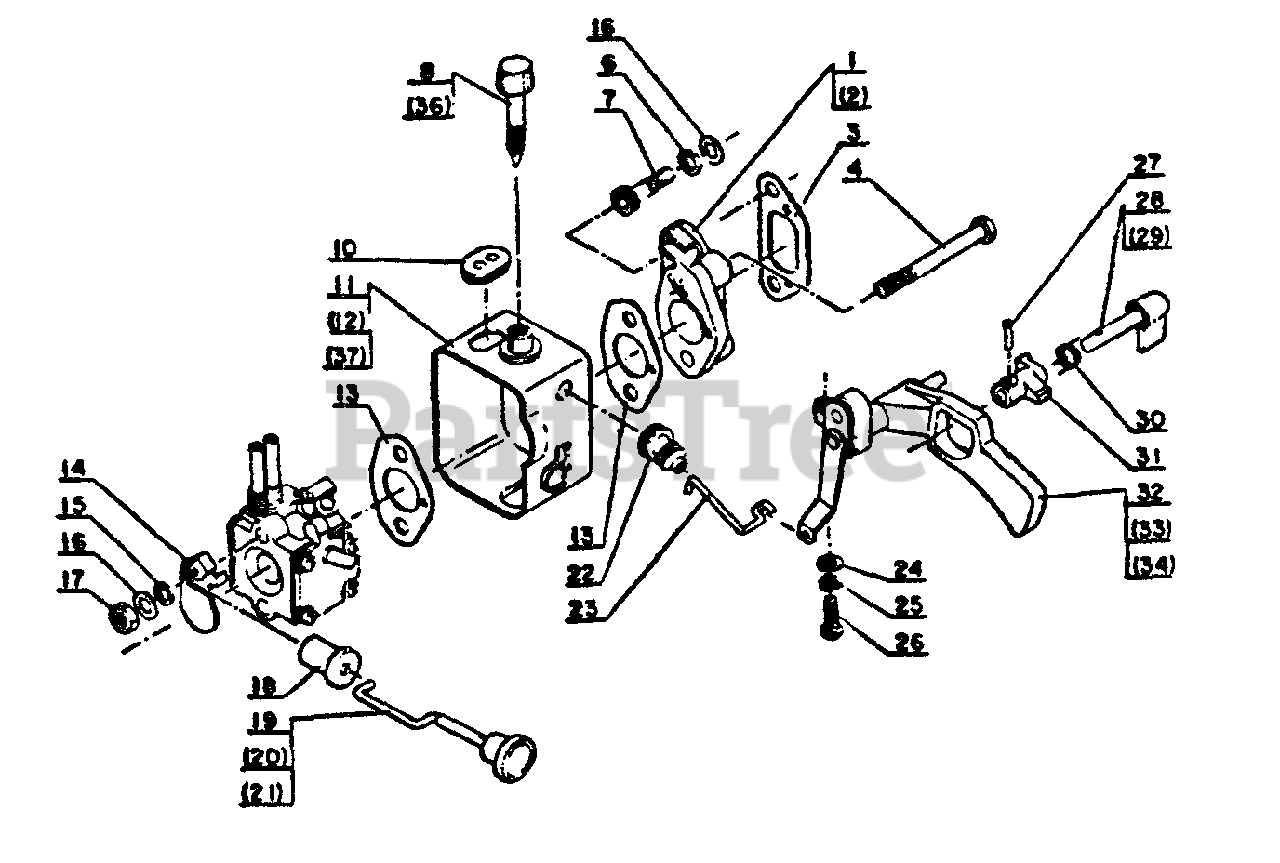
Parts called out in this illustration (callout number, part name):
1	CASE, CARBURETOR
3	GASKET, INTAKE
5	WASHER
6	WASHER, SPRING 5
7	BOLT - 5×20
8	SCREW, IDLE ADJUST
10	GROMMET
11	CASE, CARBURETOR
13	GASKET, INTAKE
14	SHUTTER, CHOKE
15	WASHER 5.2×8×0.8T
16	WASHER, FLAT 5.5×10×0.8
17	LOCKNUT - 5
18	GROMMET
19	ROD, CHOKE
22	RUBBER BUSH
23	ROD, THROTTLE
24	WASHER 4 MM
25	WASHER, SPRING 4 MM
26	SCREW 4×14
27	PIN, SPRING
28	LEVER, THROTTLE
30	SPRING, THROTTLE LOCK
31	LOCKOUT, TRIGGER
32	TRIGGER, THROTTLE
